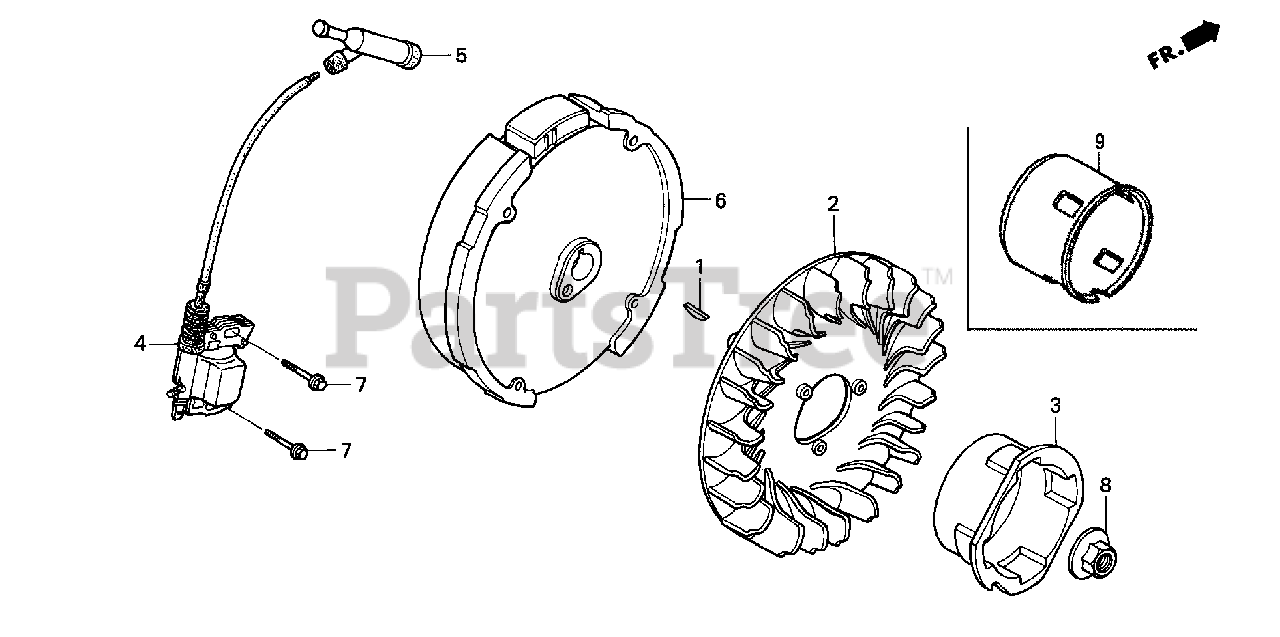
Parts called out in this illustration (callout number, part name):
1	KEY, SPECIAL WOODRUFF (25X18)
2	FAN, COOLING
3	PULLEY, STARTER
4	COIL ASSY., IGNITION
5	CAP ASSY., NOISE SUPPRESSOR (NICHIWA Y-EZ RTFM256)
6	FLYWHEEL
7	BOLT, FLANGE (6X25)
8	NUT, SPECIAL (14MM)
9	PULLEY, STARTER
